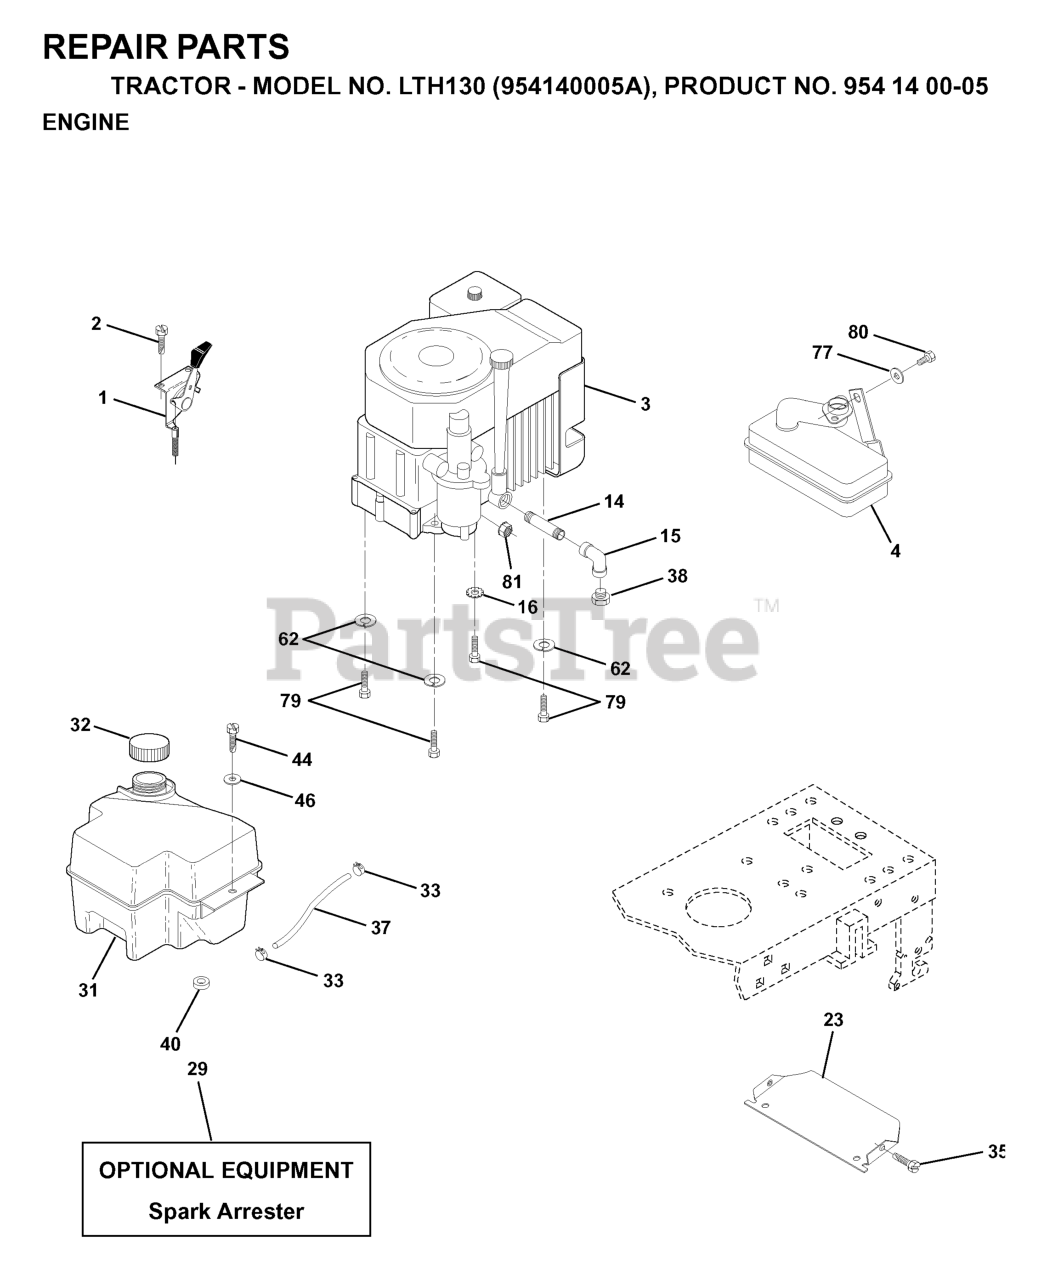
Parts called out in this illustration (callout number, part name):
2	SCREW LT
4	MUFFLER LT 12.5
14	Std. Pipe Nipple 3/8 - 18 NPT x 3 1/2
15	ELBOW
16	WASHER EXT TOOTH LOCK 5/16
23	SHIELD HEAT
29	KIT.SPARK ARRESTOR 794945 B&S
31	FUEL TANK
32	FUEL CAP
33	HOSE CLAMP
35	SCREW.THDROL.5/16-18X3/4.TTY
37	LINE.FUEL.20
40	BUSHING.SNAP.NYL.BLK.
44	SCREW HEX CRT
62	WASHER.LOCK.HVY.HLCL.SPR.5/16
77	WASHER
79	BOLT, HEX
80	Bolt, Hex Head, Fin. 5/16-18 x 1/2
81	NUT FLANGE 1/4-20 STARTER NUT
